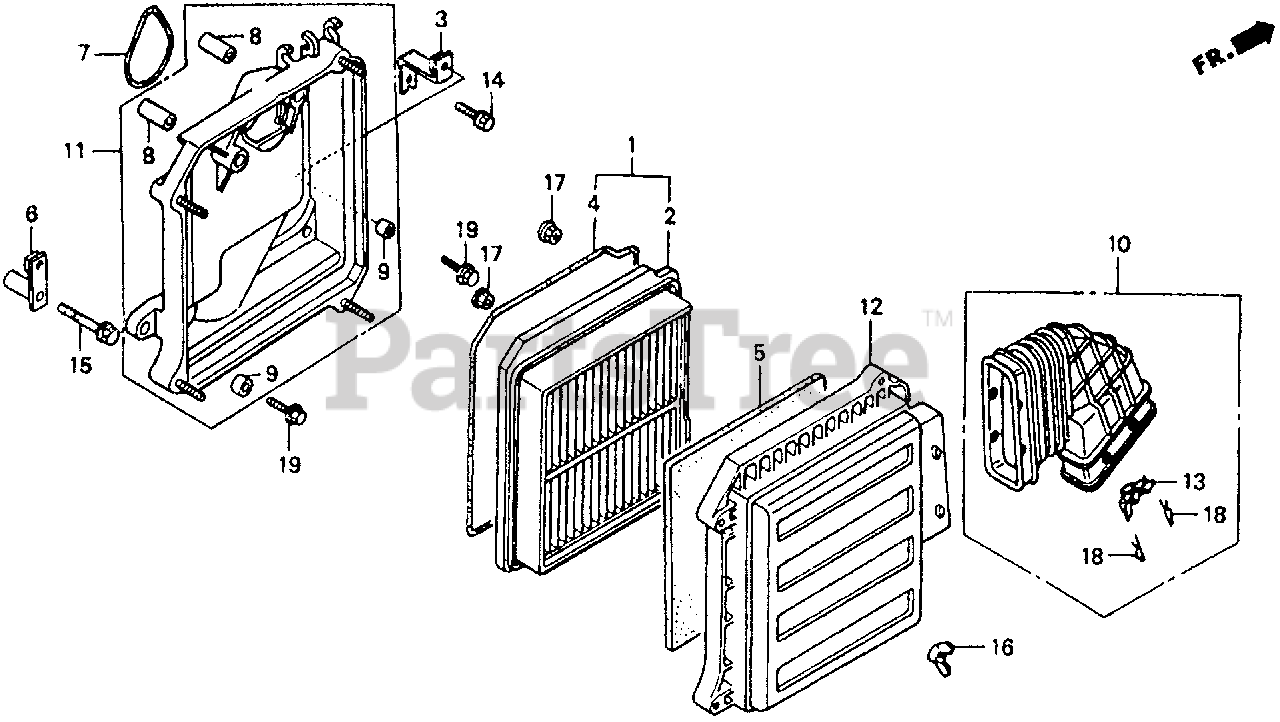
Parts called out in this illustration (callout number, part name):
1	ELEMENT KIT, AIR CLEANER
2	ELEMENT KIT, AIR CLEANER
3	BRACKET, R. AIR CLEANER
4	GASKET, ELEMENT
5	FILTER (OUTER)
6	BRACKET, L. AIR CLEANER
7	GASKET, AIR CLEANER
8	COLLAR, AIR CLEANER
9	COLLAR B, AIR CLEANER
10	TUBE, AIR IN.
11	CASE, MUFFLER
12	COVER, MUFFLER
13	CLIP, HARNESS
14	BOLT, FLANGE (6X14)
15	BOLT, FLANGE (6X45)
16	WINGNUT, TOOL BOX SETTING
17	NUT, FLANGE (6MM)
18	PIN, LOCK (6MM)
19	BOLT, FLANGE (6X20)
